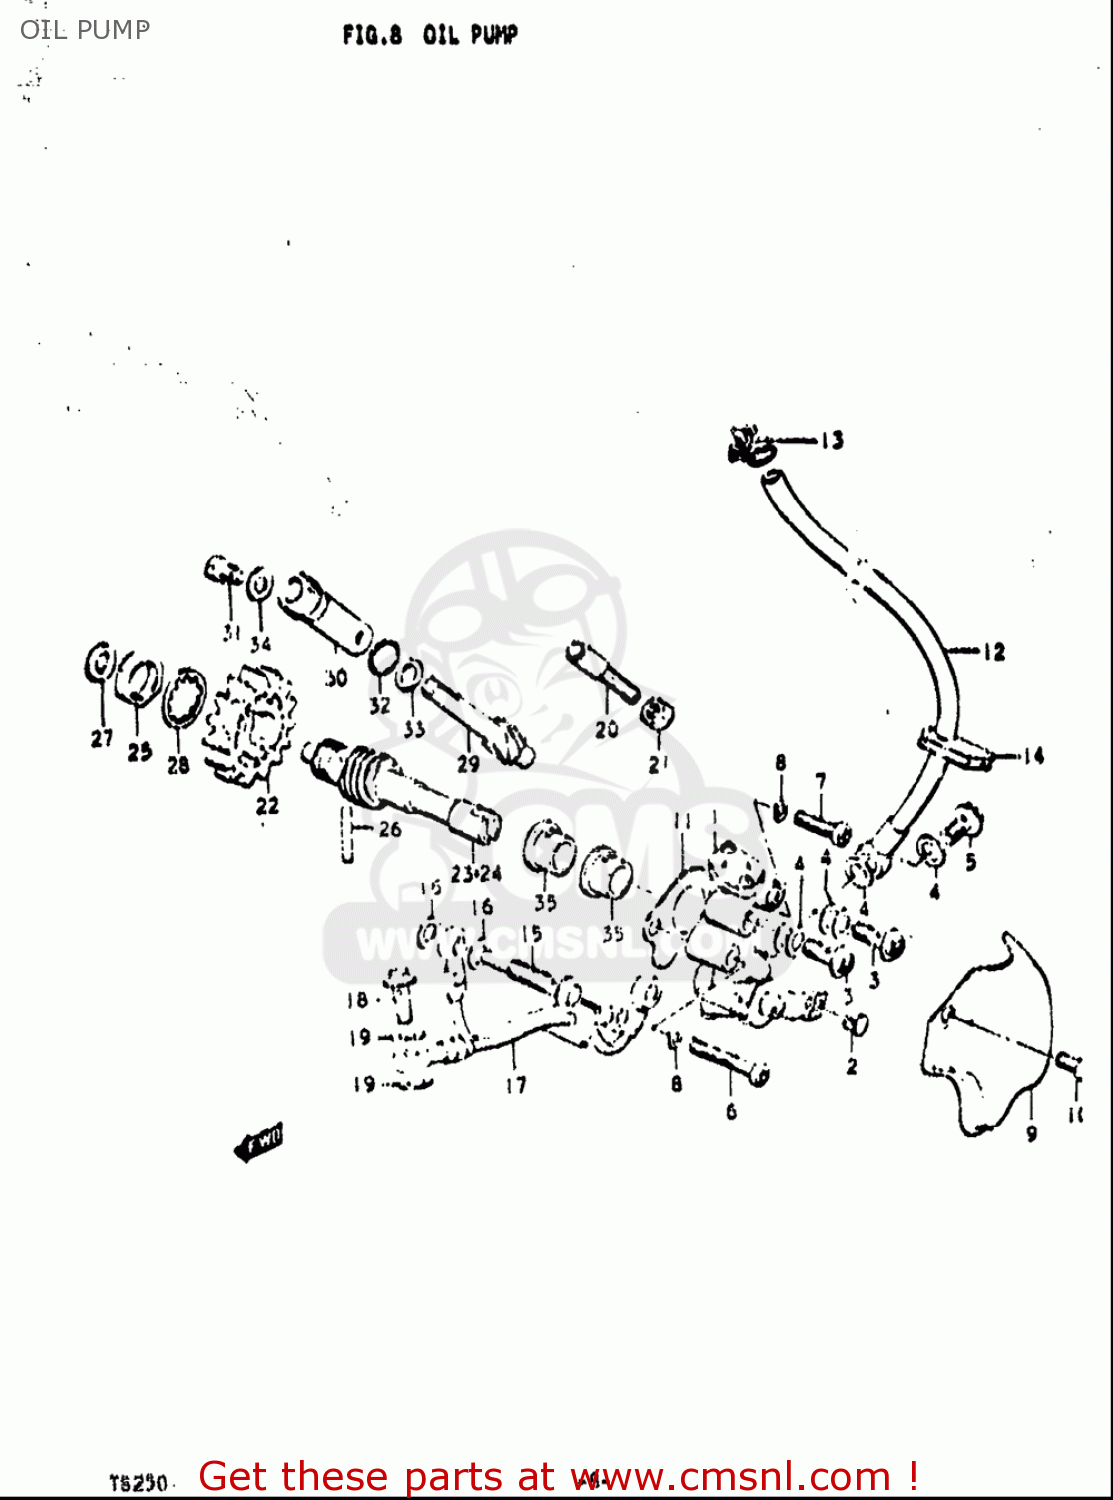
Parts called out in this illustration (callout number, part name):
2	TERMINAL,CABLE
3	UNION BOLT
4	GASKET(6.2X11X1).2 (NAS)
5	UNION BOLT
6	SCREW
7	SCREW
8	WASHER,LOCK
9	CAP,OIL PUMP INSPECTION
10	SCREW
11	GASKET,OIL PUMP (NAS)
13	CLAMP
14	GROMMET
15	UNION
18	UNION BOLT
20	BOLT
21	NUT
22	GEAR,OIL PUMP DRIVE
26	ROLLER(4X23.8)
31	BOLT
32	O RING(D:1.3,ID:9.6)
33	WASHER(8X13.7X1)
34	WASHER
